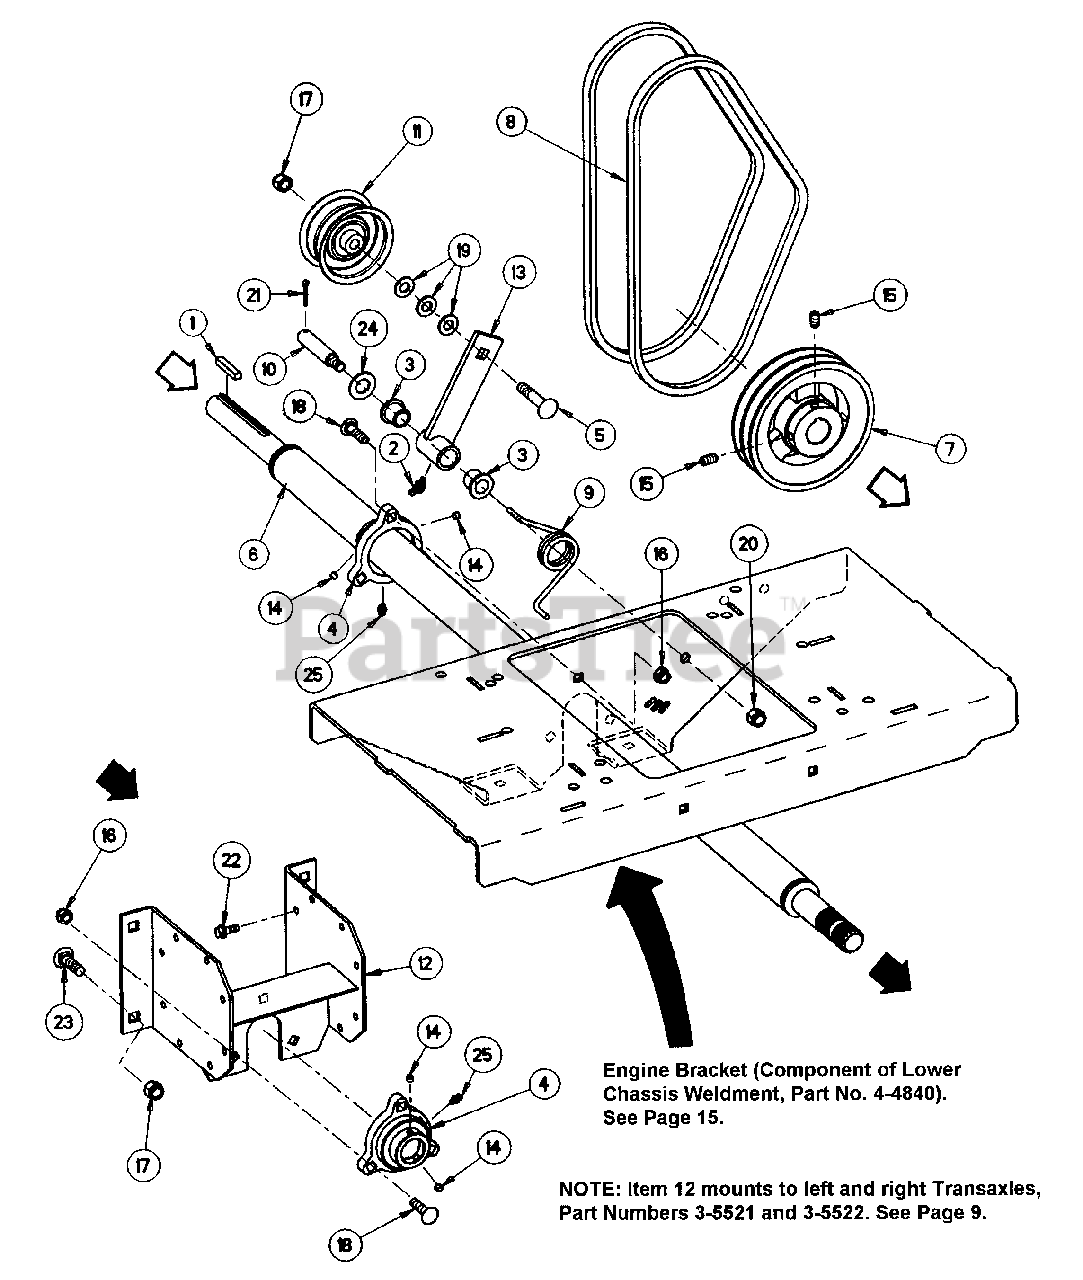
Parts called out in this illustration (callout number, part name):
1	KEY, 1/4 Square x 2"
2	FITTING, Lube
3	BUSHING
4	ASSEMBLY, Bearing
5	BOLT, 3/8-16 x 2" Square Neck Carriage, Grade 2
6	DRIVESHAFT, Deck
7	PULLEY, Double V (5.45 O.D.)
8	BELT, Deck Drive (HA 37.25)
9	SPRING, Tension
10	PIN, 3/8-24
11	FLAT IDLER, 2.75 O.D. x 1-1/4" Wide
12	BEARING MOUNT (Weldment)
13	IDLER ARM (Weldment)
14	SET SCREW, 1/4-20 x 1/4" Cone Point
15	SET SCREW, 5/16-18 x 5/8" Knurled Cup Point
16	NUT, 5/16-18 HEX NYLON LOCK
17	NUT, 3/8-16 HEX NYLON LOCK
18	BOLT, 5/16-18 x 1-1/4" Grade 5
19	WASHER, 3/8" Flat
20	NUT, 3/8-24 Hex Nyloc
21	COTTER-PIN, 1/8 x 3/4"
22	SCREW, 1/4-20 x 5/8", Hex Flange Lock, Grade 5
23	BOLT, 3/8-16 x 1-1/4" Short Neck Carriage, Grade 5
24	WASHER, 9/16 Flat
25	LUBE FITTING, Straight (press-fit for .187 dia. Hole)
